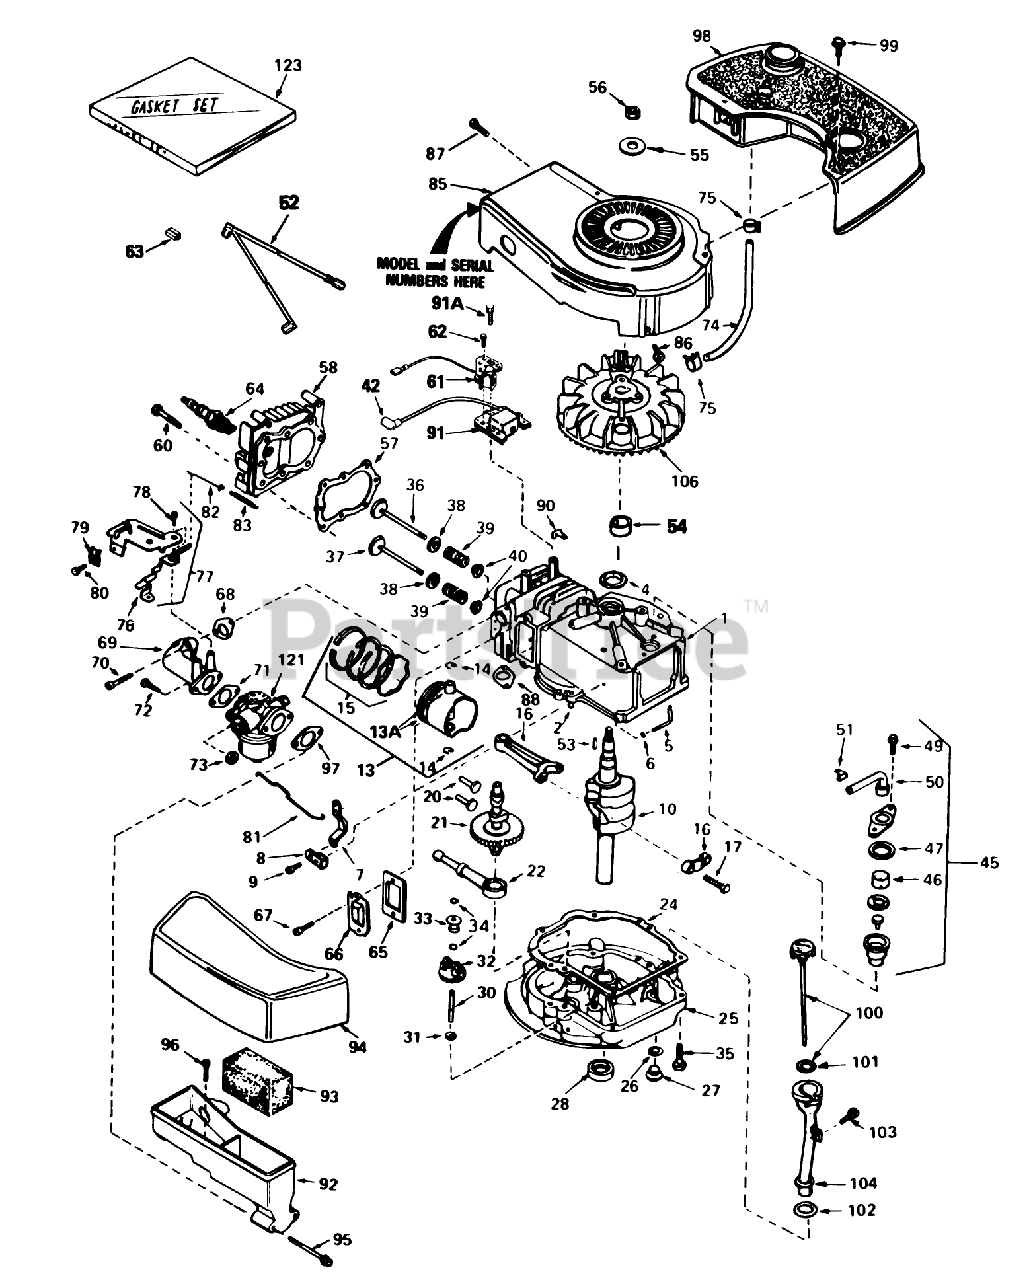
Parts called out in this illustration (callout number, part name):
1	Cyiinder Assy. (Incl. Ref. #2, 4 105)
2	Pin-Dowel
4	Seal-Oil
5	Rod, Governor (Incl. No. 36)
6	Washer-Flat
7	Governor Lever
8	Clamp-Lever, Governor
9	Screw
10	Crankshaft
13	Piston, Pin Ring Assy. (Std.) (Incl. Ref. #13A, 14 15)
13	Piston, Pin Ring Assy. (.010 oversize) (Incl. Ref. #13A, 14 15)
13	Piston, Pin Ring Assy. (.020 oversize) (Incl. Ref. #13A, 14 15)
13A	Piston Pin Assy. (Incl . Ref. . #14) (Std.)
13A	Piston Pin Assy. (Incl. Ref. #14) (.010 Oversize)
13A	Piston Pin Assy. (.020 oversize) (Incl. Ref. #14)
14	Ring-Retaining, Piston Pin
15	Ring Set (Std.)
15	Ring Set (.020" OS)
15	Ring Set (.010" OS)
16	Rod Assy., Connecting (Incl. Ref. #17)
17	Bolt-Rod, Connecting
20	Lifter-Valve
21	Camshaft(Mech.Comp. Release)
22	Oil Pump ASM
24	Gasket, Mounting
25	Flange Assy., Mounting (Incl. Ref. #26thru 30)
26	Gasket-Oil Drain
27	Plug Oil Drain
28	Seal Oil
30	Shaft-Governor
31	Washer-Flat
32	Governor Gear ASM
33	Spool-Governor
34	Ring-Retaining
35	Screw (1/4-20 x 1-1/4)
36	Valve, Intake (Std.) (Incl. #40)
36	Valve, Exhaust (1/32" oversize) (Incl. #40)
37	Valve, Exhaust (Std.) (Incl. #40)
37	Valve, Exhaust (1/32" oversize) (Incl. #40)
38	Cap-Upper Valve Spring
39	Spring-Valve
40	Cap-Valve, Spring
42	Cover-Spark Plug
45	Breather Assy. (Incl. Ref. #46 thru 51)
46	Element-Breather
47	Gasket-Breather
49	Screw (10-24 x 9/16)
50	Tube, Breaker
51	Clip, Breather
52	Wire-Ground
53	Key-Flywheel
54	Spacer
55	Washer-Belleville
56	Nut-Flywheel
57	63573 GIL 42 SNWTHW
58	Head-Cylinder
60	Screw (5/16-18x1-1/2)
61	Coil, Alternator
62	Screw (8-32x27/64)
63	Connector-Body
64	Plug, Spark (J17LM or equiv.)
64	Plug, Spark (Champion RCJ-8)
65	Gasket-Breather
66	Cover-Valve
67	Screw
68	Gasket-Intake
69	Pipe, Intake (Incl. No. 68)
70	Screw (1/4-20 x 1)
71	Gasket-Carburetor
73	Nut and Lock Washer (1/4-28)
74	Line-Fuel
75	Clamp-Line, Fuel
76	Lever Control
77	Control Assy., Speed (Incl. Nos, 76, 78 89)
78	Screw, Hex Washer Hd Shoulder Self-Tap
79	Conduit
80	Screw (10-32 x 3/8)
81	Link-Throttle
82	Link Governor Spring
83	Spring Governor
85	Housing-Blower
86	Screw (1/4-20x19/32)
87	Screw (10-24 x 9/16)
88	Gasket Exhaust
90	Clip-Wire
91	Solid State
91A	Screw
92	Body Air Cleaner
93	Filer, Air
94	Cove, Air Cleaner
95	Screw Fil Hd.
96	Screw, Hex Hd.
97	Gasket-Air Cleaner
98	Tank-Fuel
99	Screw (10-32 x 35/64)
100	Dipstick, Oil (Incl. Ref. #101)(Twist Lock)
101	O-Ring
102	Gasket
103	Screw (10-32 x 1/2)
104	Tube-Oil Fill
106	Flywheel
121	Carburetor (Incl. Ref. #71)
123	Gasket Set
